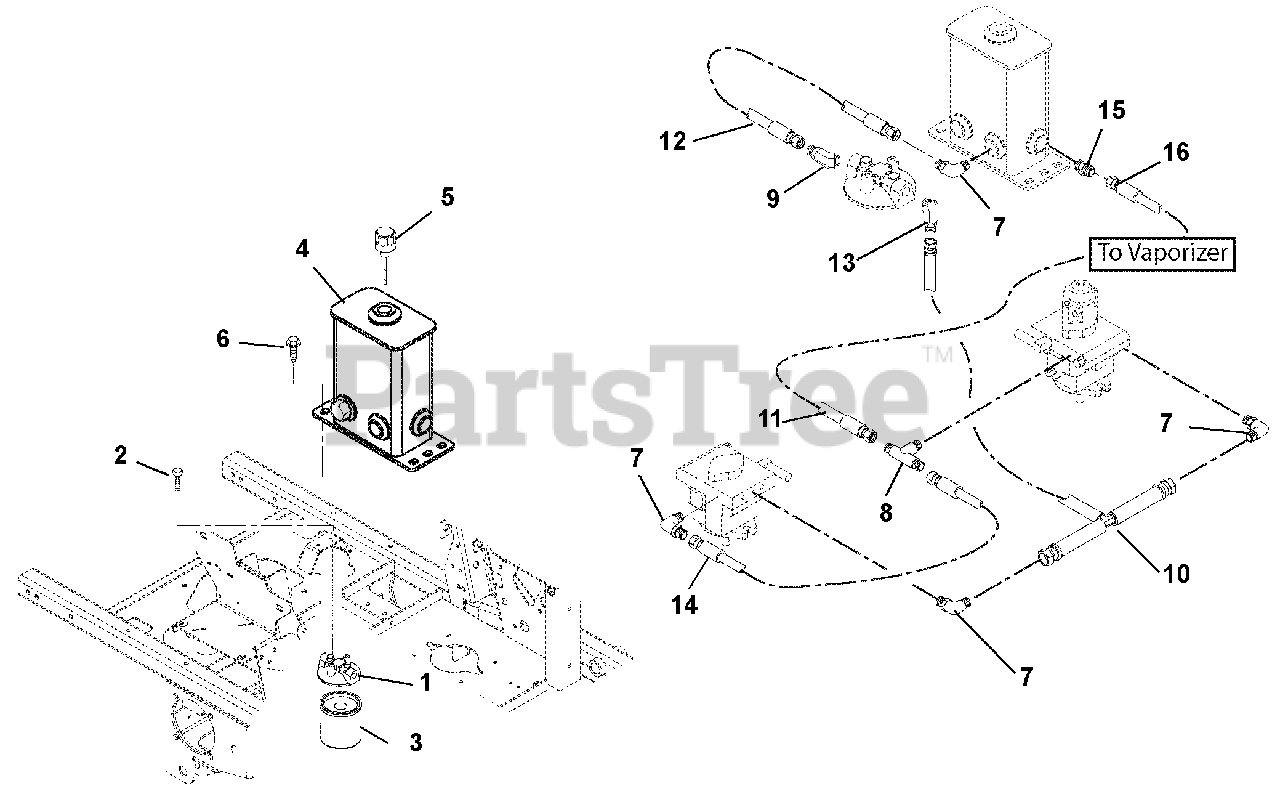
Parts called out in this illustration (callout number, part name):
1	Head, Filter
2	Bolt, Hex .25-20 x .50 Epoxy Grade 5
3	Oil Filter
4	Weldment, Formed Hydraulic Tank – 2 PORT
5	Dipstick, Breather
6	Screw, Tapping .38-16 x .75 Hex Washer Head
7	Fitting, Hydraulic, 90 Degree Elbow, Steel M8F-M80
8	Fitting, Hydraulic Tee M80-M80-M80
9	Fitting, Hydraulic Straight M80-M80
10	Hose, Tee Assembly, .50
11	Hose, Hydraulic .50-31 F8F0-F8F0
12	Hose, Hydraulic Molded
13	Fitting, Hydraulic 45° M80-M80
14	Hose, Hydraulic
15	Fitting, Hydraulic 45 Degree M8F-M80
16	Hose, Hydraulic .50-13-OK F8F0-F8F0
